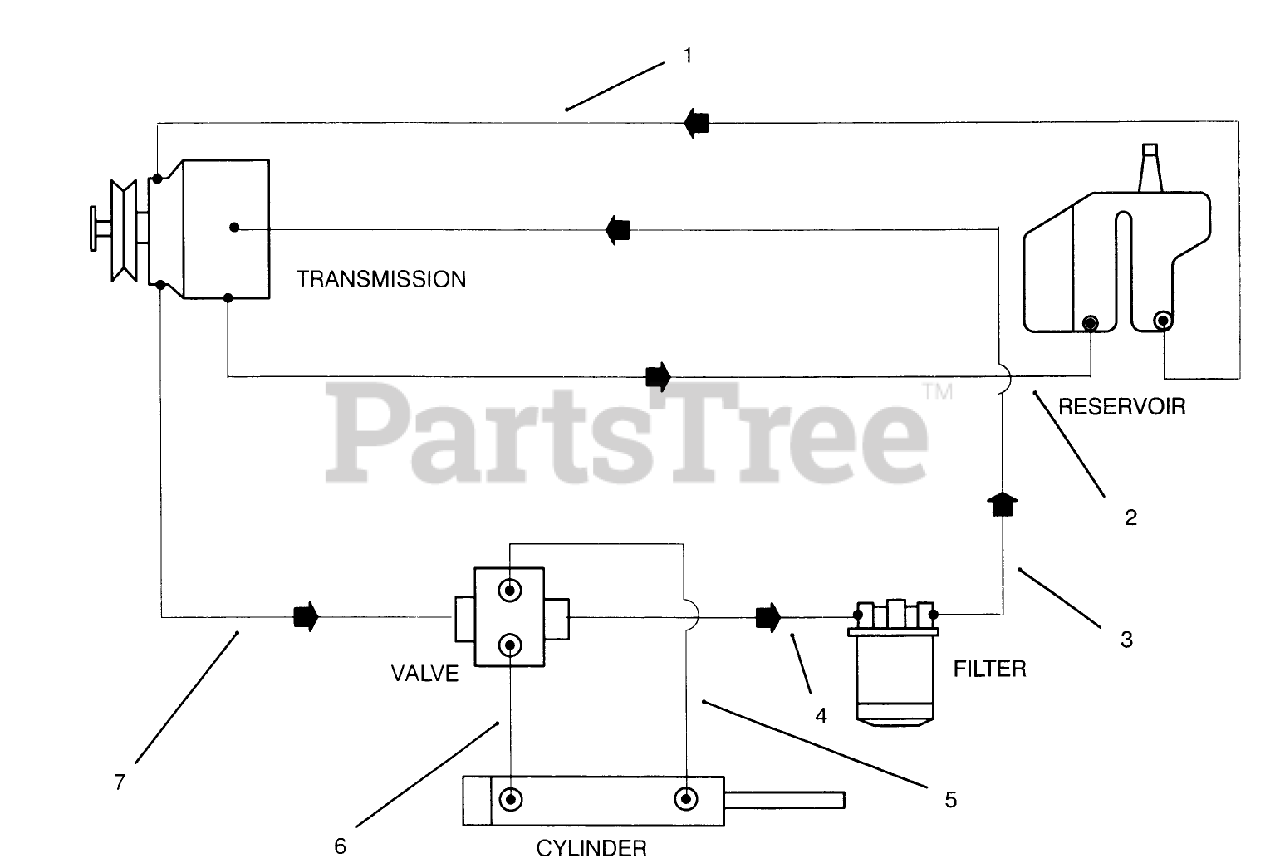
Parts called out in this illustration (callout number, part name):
1	HOSE ASM
2	TUBE ASM
3	HOSE ASM
4	HOSE ASM
5	HOSE ASM
6	HOSE ASM
7	HOSE ASM
